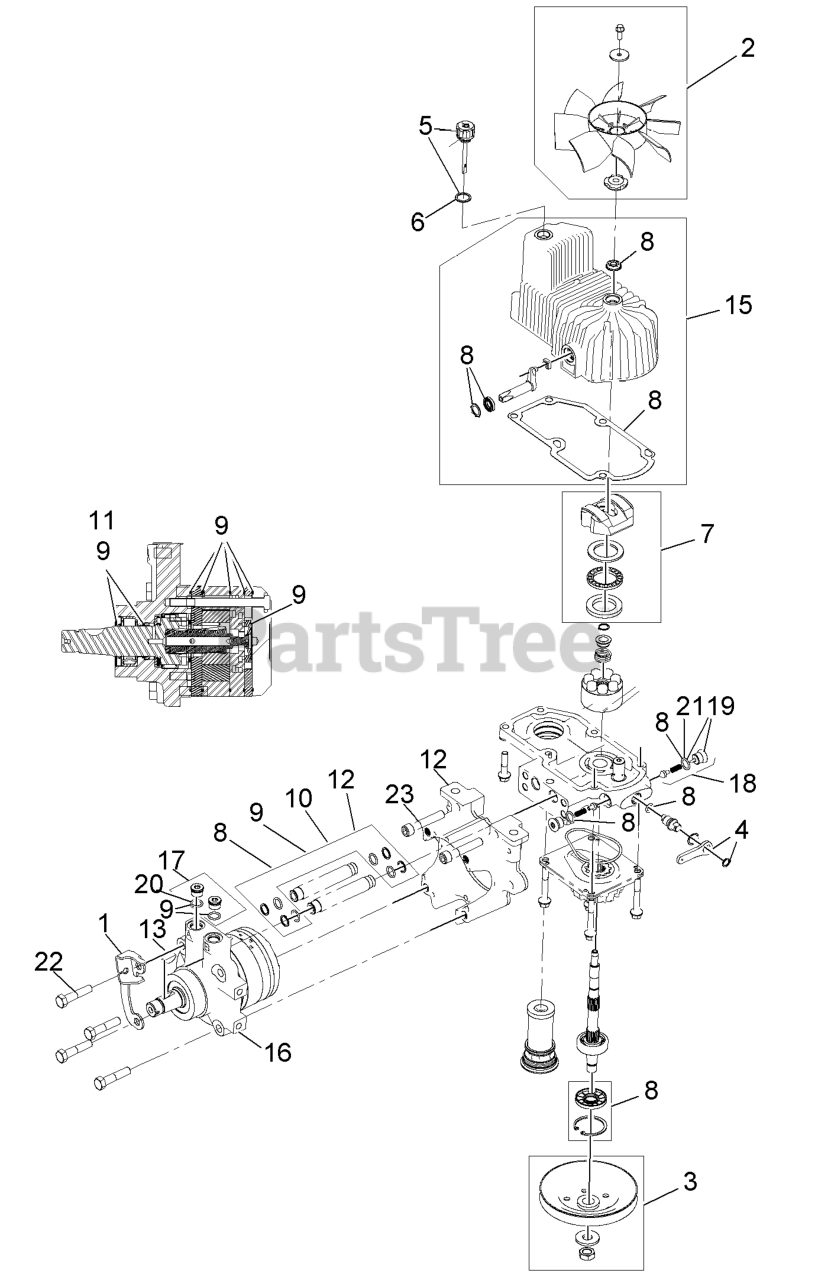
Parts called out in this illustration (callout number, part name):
1	BRACKET-ANCHOR, CABLE
2	FAN KIT
3	PULLEY KIT
4	HANDLE-BYPASS VALVE, HYDRO
5	DIPSTICK-HYDRO W/GASKET
6	GASKET-DIPSTICK, HYDRO
7	SWASH BLOCK KIT
8	PUMP SEAL KIT
9	MOTOR SEAL KIT
10	TUBE SEAL KIT
11	OUTPUT SHAFT SEAL KIT
12	NOSE CUP-UHT
13	KEY-WOODRUFF
15	HOUSING-HYDRO, RH
16	MOTOR-HYDRAULIC RH 240CC
17	MAGNETIC PLUGS SERVICE KIT
18	CHECK VALVE ASM
19	PLUG-CHECK (W/O-RING)
21	O-RING-CHECK VALVE
22	SCREW HH
23	SCREW-HSH
